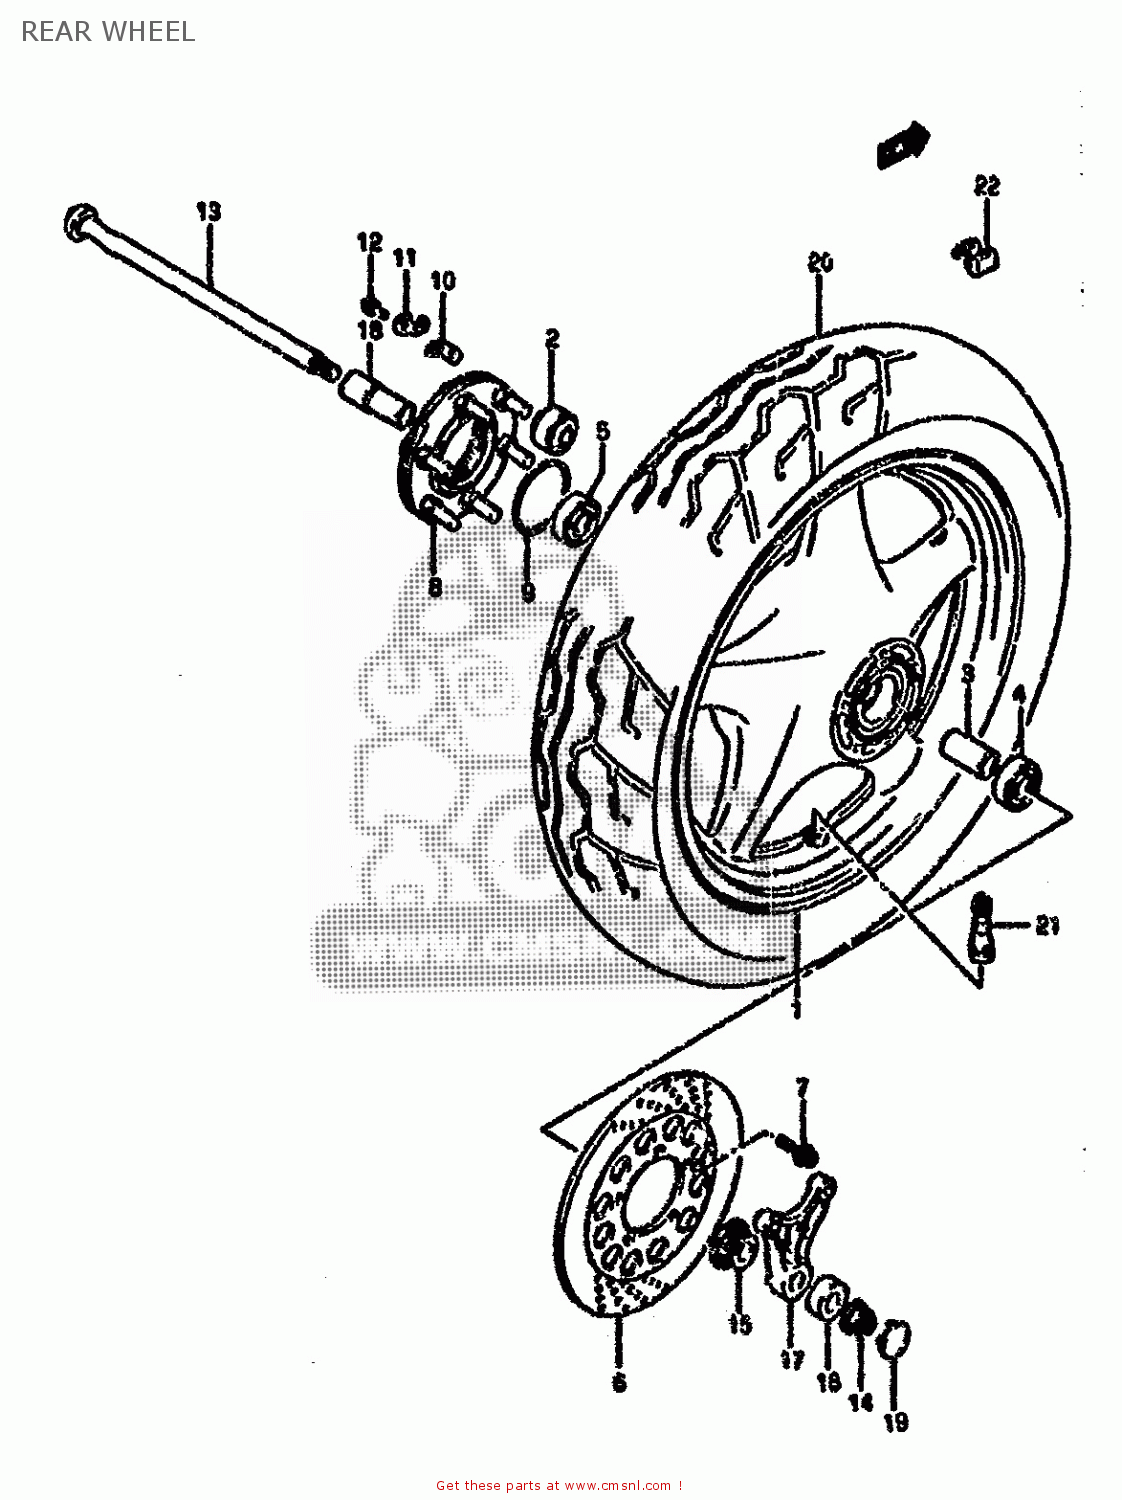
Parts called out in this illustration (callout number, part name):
1	WHEEL SET,REAR (17XMT3)
2	BUSH
3	SPACER,REAR HUB BEARING
4	BEARING
5	BEARING
6	DISC,RR BRAKE
7	BOLT, REAR
8	JOINT ASSY,RR HUB DRIVEN
9	O RING(D:2.1,ID:65)
10	WASHER,THRUST(T:1.6)
11	WASHER
12	BOLT(6X16)
13	AXLE,REAR
14	NUT
15	SPACER,RR AXLE,R
16	SPACER,RR AXLE,R
17	BRACKET,RR,CALIPER
18	SPACER,RR AXLE,L
19	CAP,RR AXLE,R
20	TIRE 150/70 817 69H,ME
21	VALVE ASSEMBLY,WHEEL,TR412
22	BALANCER,WHEEL
